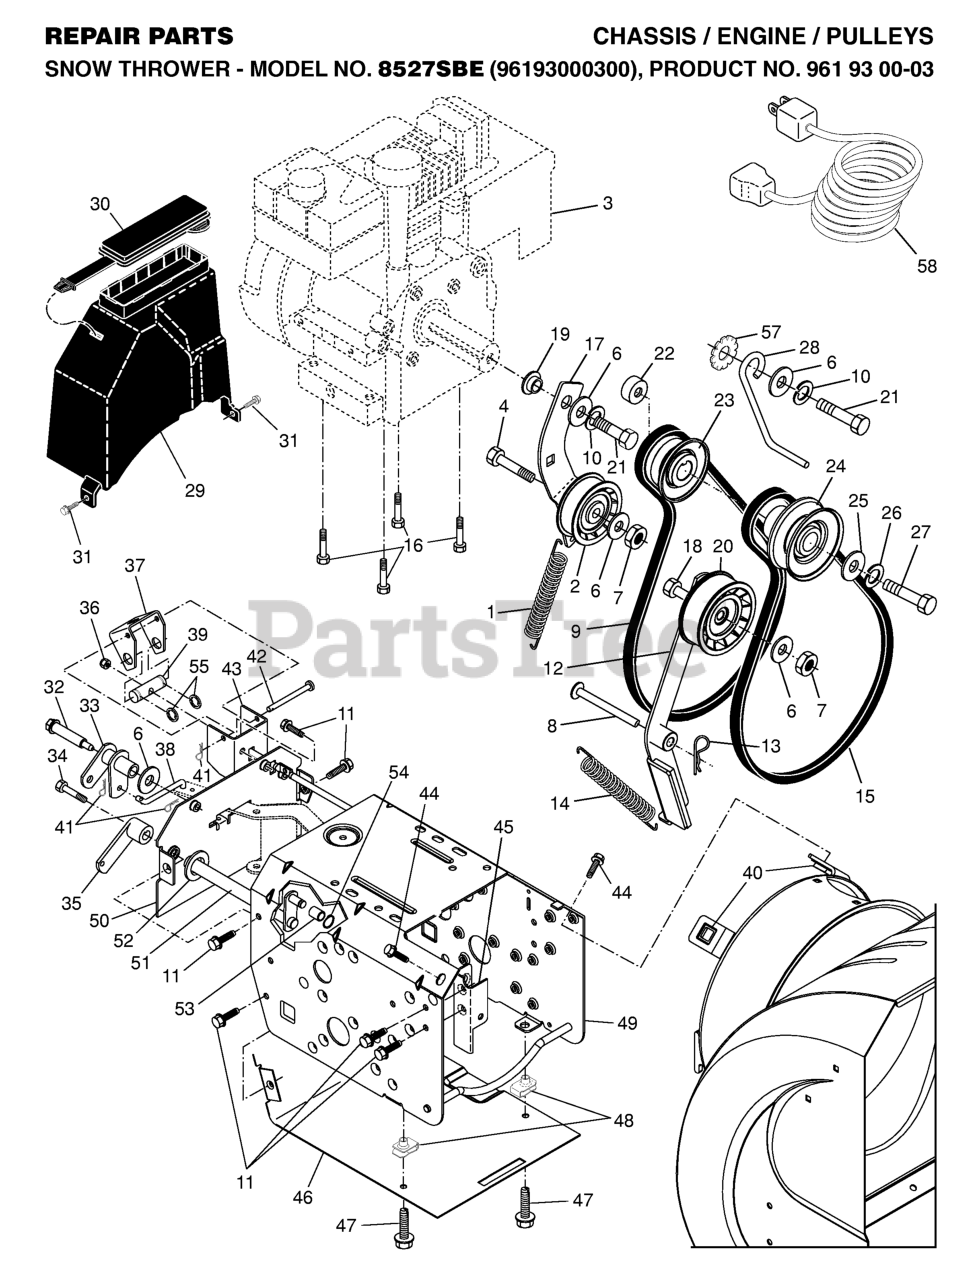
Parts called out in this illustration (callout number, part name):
1	RP SPRING, TRACTION IDLER
2	PULLEY.W/SPACER.2.25
4	BOLT.5/16-18X1-1/4 FULL.THREAD
6	STEEL WASHER
7	NUT.CENTERLOCK.5/16-
8	PIN, IDLER PIVOT
9	V-BELT, TRACTION DRIVE
10	WASHER.LOCK.HVY.HLCL.SPR.5/16
11	Screw 5/16-18 x 1/2 Hex, Self Tapping 5/16-18 x 1/2
12	ARM ASSEMBLY, IMPELLER IDLER
13	RETAINER CLIP PM
14	SPRING, BRAKE
15	V-BELT, IMPELLER DRIVE
16	BOLT, ENGINE, 3/8-16
17	IDLER ARM
18	HEX BOLT
19	RP BUSHING, IDLER PIVOT
20	PULLEY.W/SPACER.2.75
22	SPACER, ENGINE PULLEY
23	PULLEY,ENGINE TRACTION DRIVE
24	PULLEY, ENGINE IMPELLER DRIVE
26	LOCKWASHER
27	SCREW, HEX HD 3/8-24 X 1-3/8
28	BELT.GUIDE.RH
29	COVER.ASM.BELT/STORAGE
30	COVER.STORAGE.SNOW
31	SCREW
32	BOLT, SHOULDER 5/16-18
33	BELLCRANK SHIFTER
35	ARM CONTROL.PM
36	NUT.71038.31-18.HEX.NYLOCK
37	BRACKET, PIVOT
38	LINK, SPEED CONTROL
39	TRUNNION, TRACTION
40	NUT, CAGE 3/8-16
41	RETAINER CLIP
42	PIN, PIVOT BRACKET
44	Capscrew, Hex Head, Flanged 3/8-16 x 1
45	BRACKET, IDLER PIVOT
46	PAN, FRAME BOTTOM
47	Screw, Hex Head 5/16-18 x 3/4
48	NUT.SPEED.5/16-18
49	FRAME ASSY
50	PLATE, FRAME END
51	CONTROL SHAFT WELDMENT
52	THRUST WASHER
53	ROLLER, ACTUATOR
54	RING.CRESENT
55	RETAINING RING LT
57	WASHER EXT TOOTH LOCK 5/16
58	CORD EXTENSION
